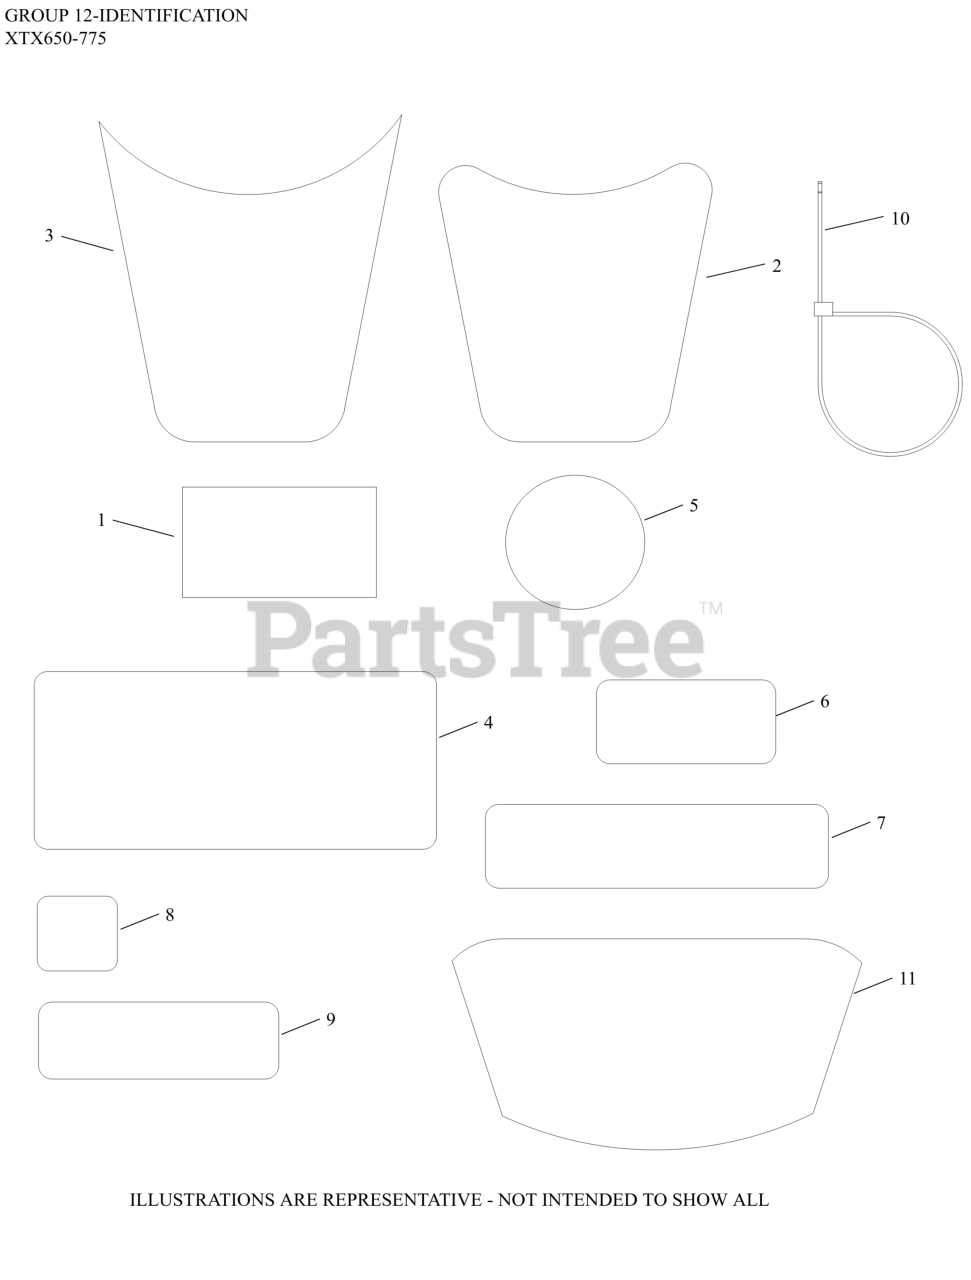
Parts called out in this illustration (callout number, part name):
1	DECAL, WARNING
8	DECAL, ON/OFF COURAGE XT7 (TTI)
11	LABEL, XTX950
